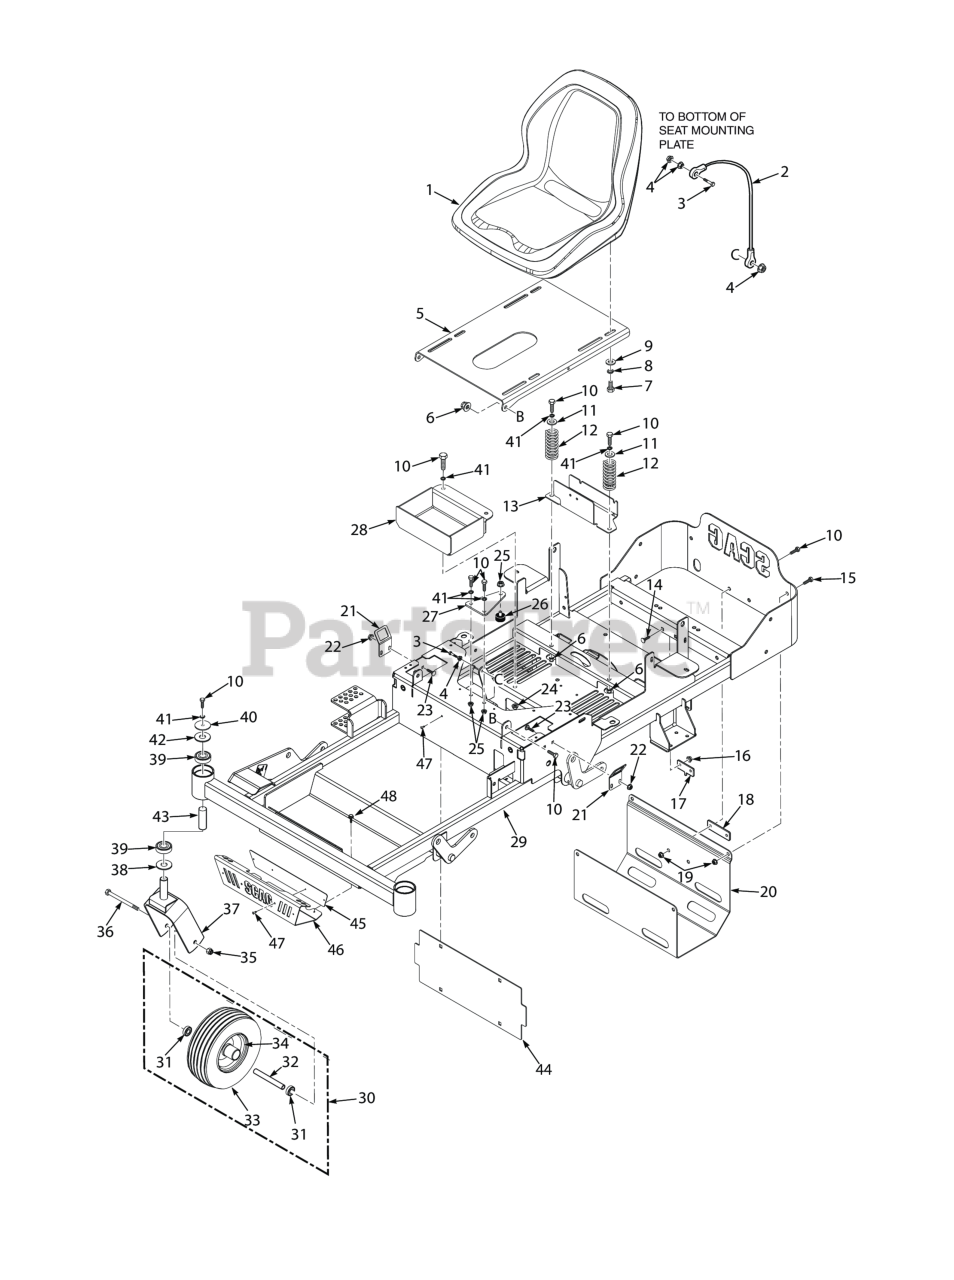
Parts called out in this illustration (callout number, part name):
1	Seat, SZL
2	Cable, Seat Stop
3	SERR. FLG. HEX HEAD CAPSCREW, 5/16-18 X 3/4
4	NUT, 1/4-20 SERRATED FLANGE HEX HEAD
5	Seat Plate w/Decal
6	Nut, Flange Elastic Stop Nut, 3/8-16
7	Bolt, Heax Head 5/16-18 x 1" (48V / 52V)
8	Lockwasher, 5/16 (.317 x .586 x .078) Helical Spring
9	Flatwasher, 5/16-.375 x .875 x .083 (35BV & 37BV-EFI)
10	Bolt, Hex Head, 3/8-16 x 1 Gr. 5
11	Flatwasher, 3/8" Special (.391 x .938 x .105)
12	Spring, Seat
13	Seat Stop
14	Bolt, 5/16-18 x .75 RHSN Carriage
15	Bolt, Hex Head, 3/8-16 x 3/4"
16	Nut, Flange Head Elastic Stop 5/16-18
17	Plate, Anti-Rotation
18	Plate, Spacer
19	NUT, 3/8-16 SERRATED FLANGE HEX HEAD
20	Skid Plate, SZL-36
21	Bracket, Switch
22	Nut, Flanged Elastic Stop 1/4-20
23	Serr. Fl. Hex Head CPSCR, 1/4-20 x 3/4"
24	Threaded insert, Hex Head (Pressed)
25	Threaded insert, Hex Head (Pressed)
26	Bumper, Rubber 5/16-18 x 5/8"
27	Battery Hold Down
28	Battery Box
29	Frame Assembly, SZL-36
30	Caster Wheel Assembly
31	Bearing
32	Spacer, Wheel Bearings
33	Tire, 11 x 4-5.00 2-Ply
34	Rim Assembly
35	HEX LOCKNUT, ELASTIC STOP, 1/2-13
36	Bolt, Hex Head 1/2-13 x 6-1/2" (52V)
37	Caster Assembly
37	Yoke Weldment, Caster
38	Spacer, Yoke
39	Bearing
40	Flatwasher, 3/8-.406 x 2.25" x .1875
41	Lockwasher, 3/8" Spring, Kawasaki FX / FS
42	Flatwasher, 7/16" (.500 x 1.25 x .083")
43	Spacer, Caster Bearing
44	Plate, Backing
45	Plate, Decal
46	Bumper. Front
47	Rivot, 3/16 x .402 POP
48	Screw, 1/4-20 x .375"
